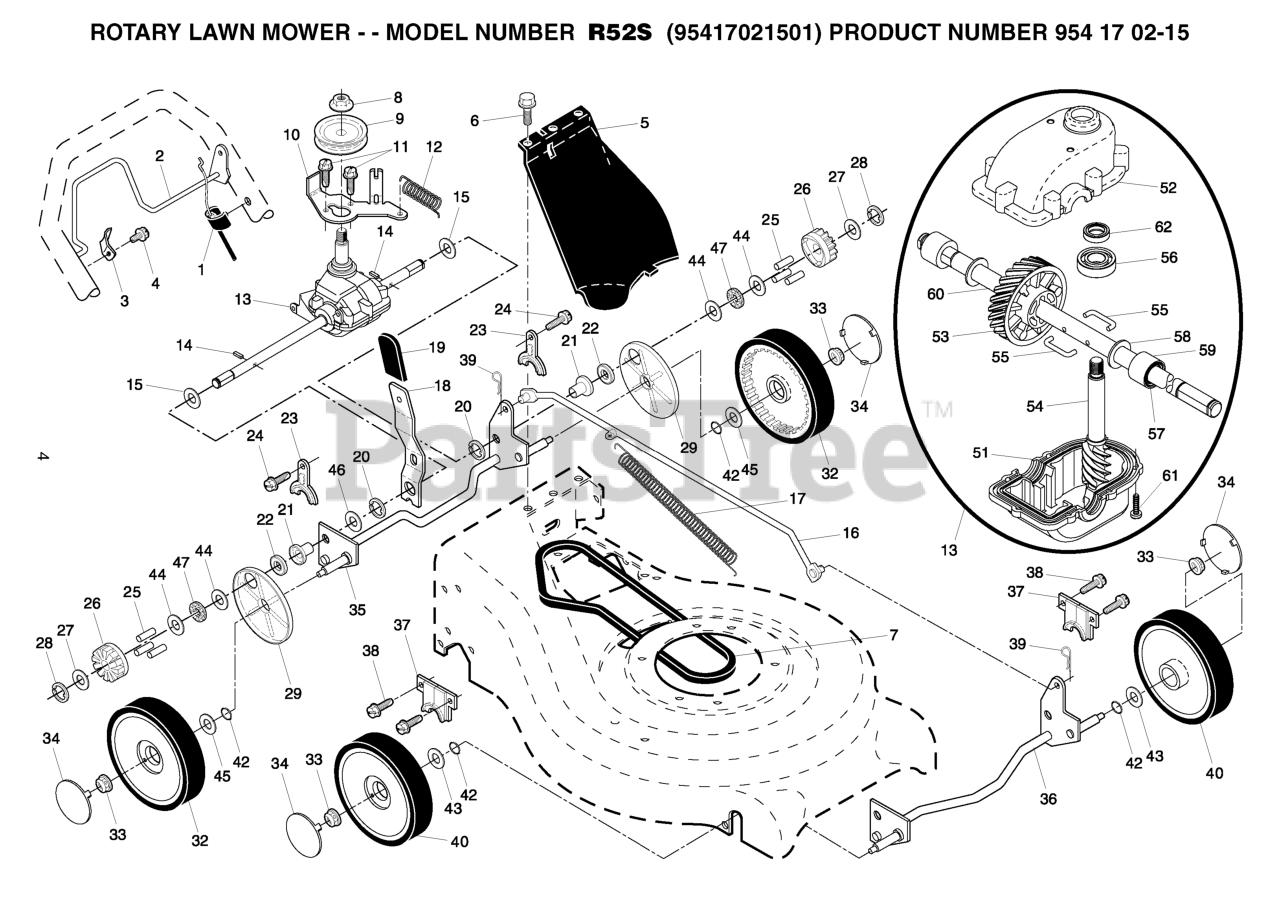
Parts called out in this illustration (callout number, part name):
1	DRIVE CABLE
3	DOWNSTOP BRACKET
5	COVER.DRIVE.21
8	FLANGED LOCKNUT 3/8-16 ZINC
10	BELT GUIDE
13	TRANSMISSION.21.RWGD.FRANCE
14	PIN.SPRING.THRUST
15	THRUST WASHER
16	ROD CONNECTING
17	SPRING
18	SPRING.SELECTOR.SPT.21
19	KNOB.EXT.ERGO.BLACK
21	RP BEARING SUPPORT
22	BEARING, BALL
23	BRACKET
25	PAWL.DRIVE.ETCHED
26	PINION.DRIVE.WALK
28	E-RING 7/16 RE
29	COVER.DUST.WHEEL
32	WHEEL 9X2
33	HEX FLANGE LOCKNT
34	HUBCAP
35	SHAFT.ASM.REAR.TORQUE
36	SHAFT ASSY FRONT
37	RETAINER.FRONT.SHAFT
39	RETAINER CLIP
40	FRONT.WHEEL.8X2
42	O-RING
43	WASHER.FLAT.1/2
44	WASHER.BELLEVILLE (3 2 LB)
45	WASHER FLUT
46	WASHER.ZINC.PLATED
51	CASE, LOWER
52	GEARCASE.HOUSING
53	GEAR.24.TOOTH.WALK.MOWER
54	SHAFT INPUT
55	WIRE, FORMED (15966)
57	SEAL.OUTPUT.SHAFT
62	SEAL INPUT SHAFT
